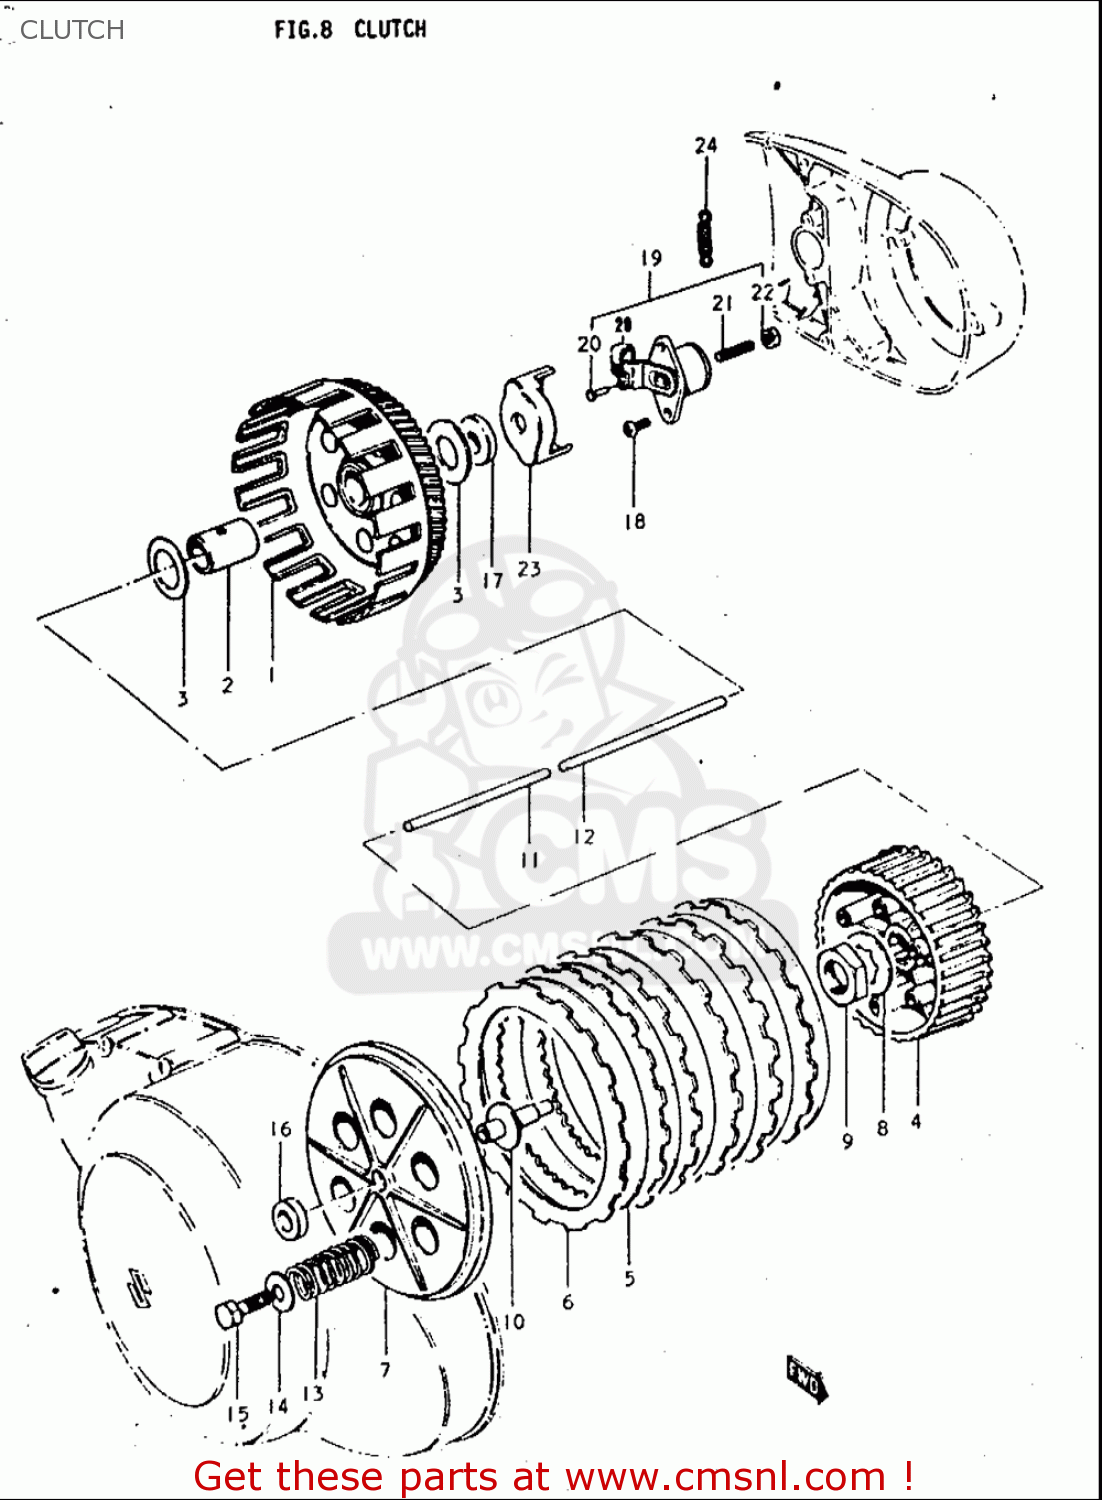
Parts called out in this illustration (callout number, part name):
2	SPACER,PRIMARY DRIVEN GEAR
3	WASHER(20X38X2)
5	PLATE,CLUTCH DRIVEN(T:2.0) (NAS)
8	WASHER,LOCK
9	NUT
11	ROD,CLUTCH PUSH
12	ROD, CLUTCH PUSH B
13	SPRING
14	WASHER(6.5X20X1.6)
16	SEAL,OIL (10X17X5)
17	SEAL,OIL (6X30X5)
18	SCREW
21	SCREW(6X25)
22	NUT
24	SPRING
